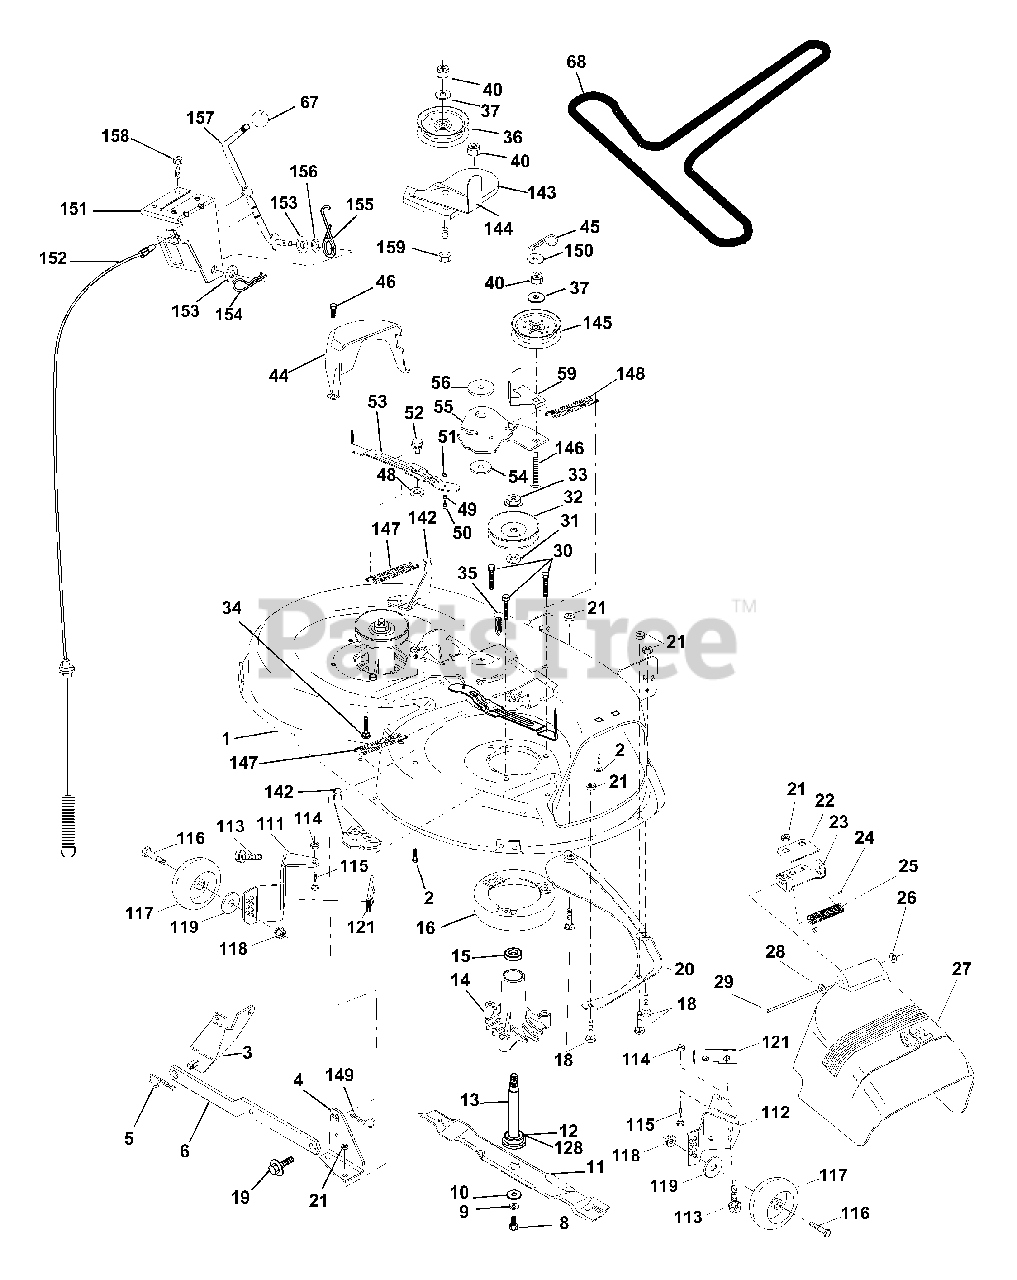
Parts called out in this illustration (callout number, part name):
1	Mower Deck Assembly, 42"
2	Bolt
3	Bracket Asm Fr. Sway Bar 3/42
4	Bracket Asm Deck 42" Sway Bar
5	Retainer Spring
6	Arm, Suspension, Rear
8	Bolt 3/8-24 x 25 Grade 8 patched
9	Washer, Lock
10	Washer,Hardened
11	Blade
12	Bearing, Ball #6204
13	Shaft Assembly, Mandrel, Vented
14	Housing, Mandrel, Vented
15	Bearing, Ball, Mandrel
16	Stripper, Vented Mower Deck
18	Bolt, Carriage 5/16-18 x 5/8
19	Bolt, Shoulder
20	Baffle, Vortex
21	Nut
22	Stiffener Bracket
23	Bracket, Deflector Mower 42"
24	Cap, Sleeve 80 x 112 Blk Mower
25	Spring, Torsion, Deflector 2 52
26	Nut, Push Phos & Oil
27	Shield, Deflector 42" Blk
28	Washer 11/32 x 5/8 x 16 Gauge
29	Rod, Hinge 42" 6 75 W/G
30	Screw Thdrol Washer Head
31	Washer, Spacer Mower Vented
32	Pulley, Mandrel
33	Nut, Toplock 9/16
34	Bolt
35	Fastener, Christmas Tree
36	Pulley, Idler, Flat
37	Washer 13/32 x 13/16 x 16 Gauge
40	Nut
44	Guard, Mandrel, LH
45	Retainer
46	Screw, Thdrol 1/4-20 x 5/8 T
48	Washer,Hardened
49	Roller Assembly, Cam Follower
50	Bolt, Shoulder #10-24 Grade 5
51	Locknut
52	Bolt, Shoulder 5/16-18 UNC
53	Arm Assembly, Pad, Brake
54	Washer,Hardened
55	Arm, Idler
56	Spacer, Retainer
59	Guard TUV Idler
67	Knob
68	V-Belt, 42" Mower
92	Nut, Lock, Hex W/Ins 3/8-16 UNC
111	Bracket, Gauge, Wheel LH
112	Bracket, Gauge, Wheel RH
113	Screw 5/16 - 18 x 3/4
114	Nut, Keps 5/16 - 18 UNC
115	Bolt, Carriage 5/16-18 x 1/2
116	Bolt, Shoulder
117	Wheel, Gauge
118	Nut Centerlock 3/8-16
119	Washer 3/8 x 7/8 x 14 Ga.
121	Bracket, Extruded
128	Washer, Felt
129	Washer 13/32 x 13/16 x 12 Ga.
130	Bolt Fin Hex 3/8-16 UNC x 1 Gr. 5
131	Bolt Rdhd Sqnk 3/8-16 UNC x 1
142	Arm Spring Brake Mower
143	Bracket Arm Idler 42"
144	Keeper Belt 42" Clutch Cable
145	Pulley Idler Flat
146	Bolt Carriage Idler
147	Spring Extension
148	Spring Return Idler
149	Retainer Spring Yellow
150	Washer 9/32 x 3/4 x 16 Ga.
151	Bracket Clutch Cable
152	Clutch Cable 42"
153	Washer Flat 3/8" Type B
154	Spring Retainer
155	Spring Retention LVR CLTCH CAB
156	Spacer Clutch Cable
157	Rod Clutch Cable 3/8"
158	Screw Hex Thd Cut 1/4-20 x 5/8
159	Bolt Rdhd Sqn 3/8-16 UNC x 1-3/4
